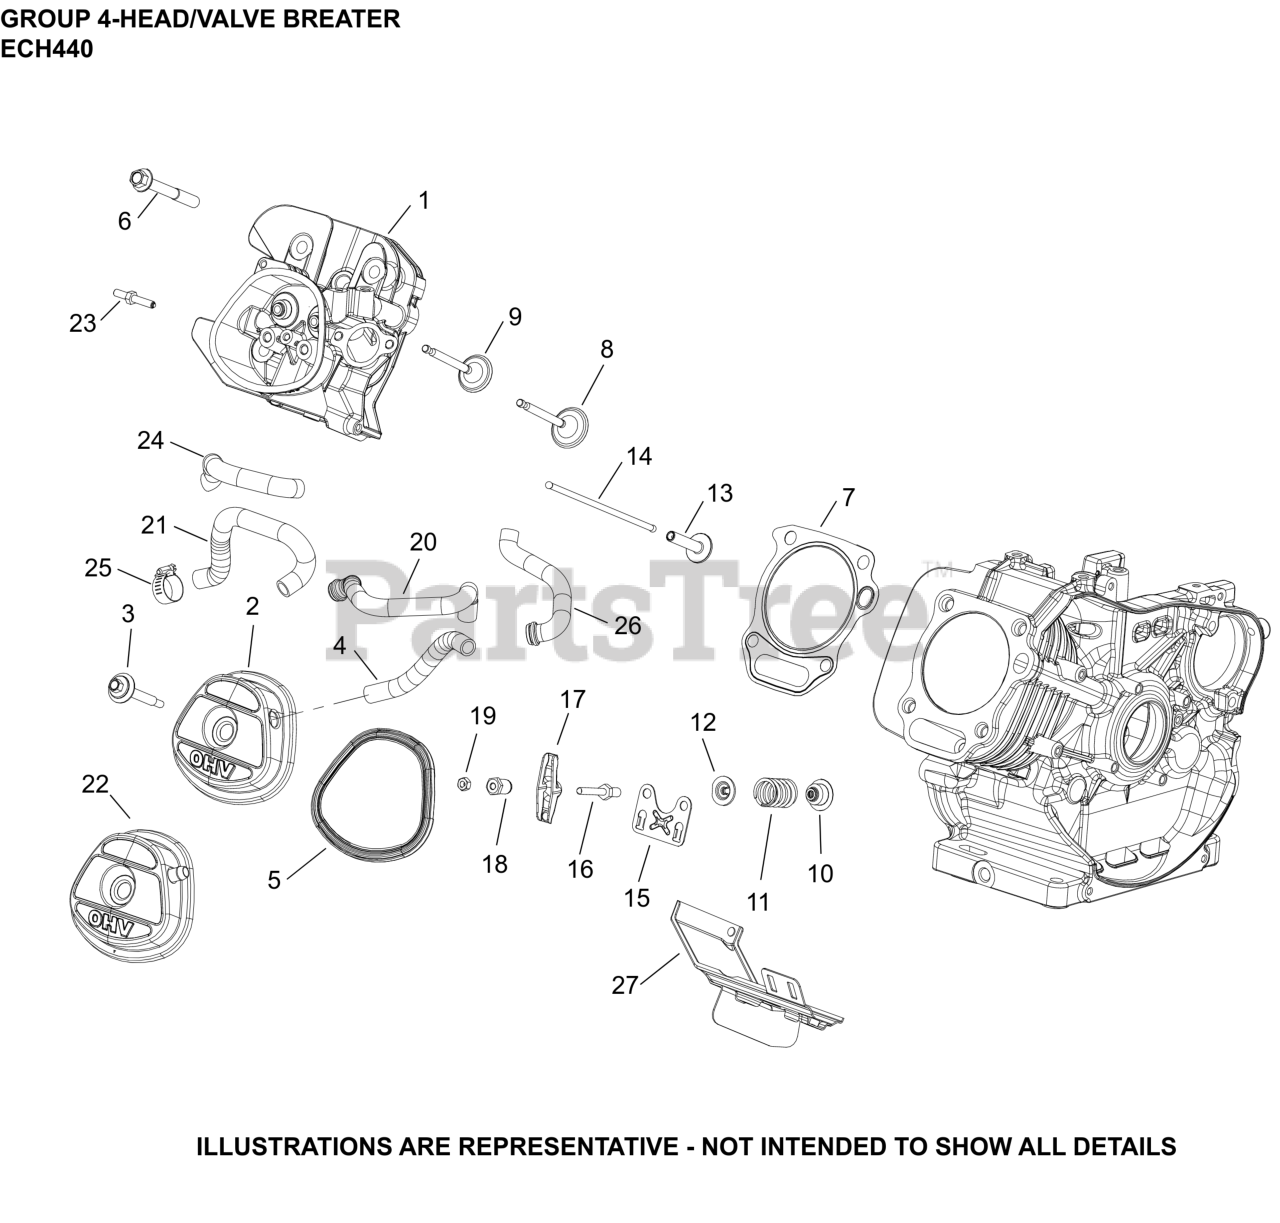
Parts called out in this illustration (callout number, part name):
1	KIT, HEAD ASSY
3	SCREW, VALVE COVER SEAL ASSY
5	GASKET, VALVE COVER
6	SCREW, HEX FLANGE CYLINDER HEAD
7	KIT, HEAD GASKET
8	VALVE, INTAKE
9	VALVE, EXHAUST
10	SEAL, VALVE STEM
11	SPRING, VALVE
12	RETAINER, VALVE SPRING
13	LIFTER, VALVE
14	ROD, PUSH
15	PLATE, PUSHROD GUIDE
16	STUD, ROCKER ARM-USE 14 072 22-S
17	ARM, ROCKER
18	PIVOT, ROCKER ARM
19	NUT, HEX JAM
21	HOSE, BREATHER
22	VALVE COVER ASSEMBLY
24	SLEEVE, ANTI ABRASION
27	SHIELD ASSEMBLY, CYLINDER
NI	PLUG, OIL FILL
